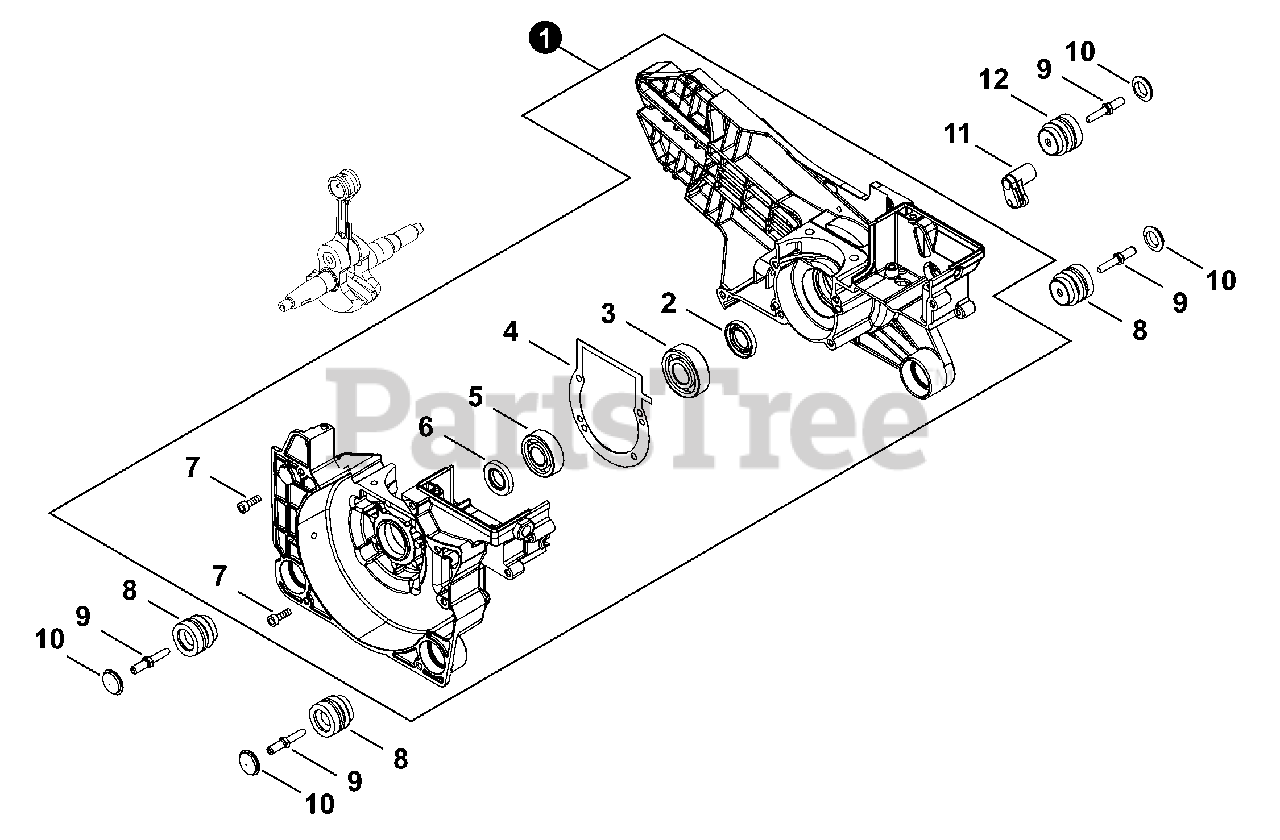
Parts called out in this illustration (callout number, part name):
1	CRANKCASE ASSY
2	SEAL, OIL 17
3	BEARING, BALL 6203
4	GASKET, CRANKCASE
5	BEARING, BALL 6202
6	SEAL, OIL 17
8	CUSHION
11	GROMMET
12	CUSHION 5
